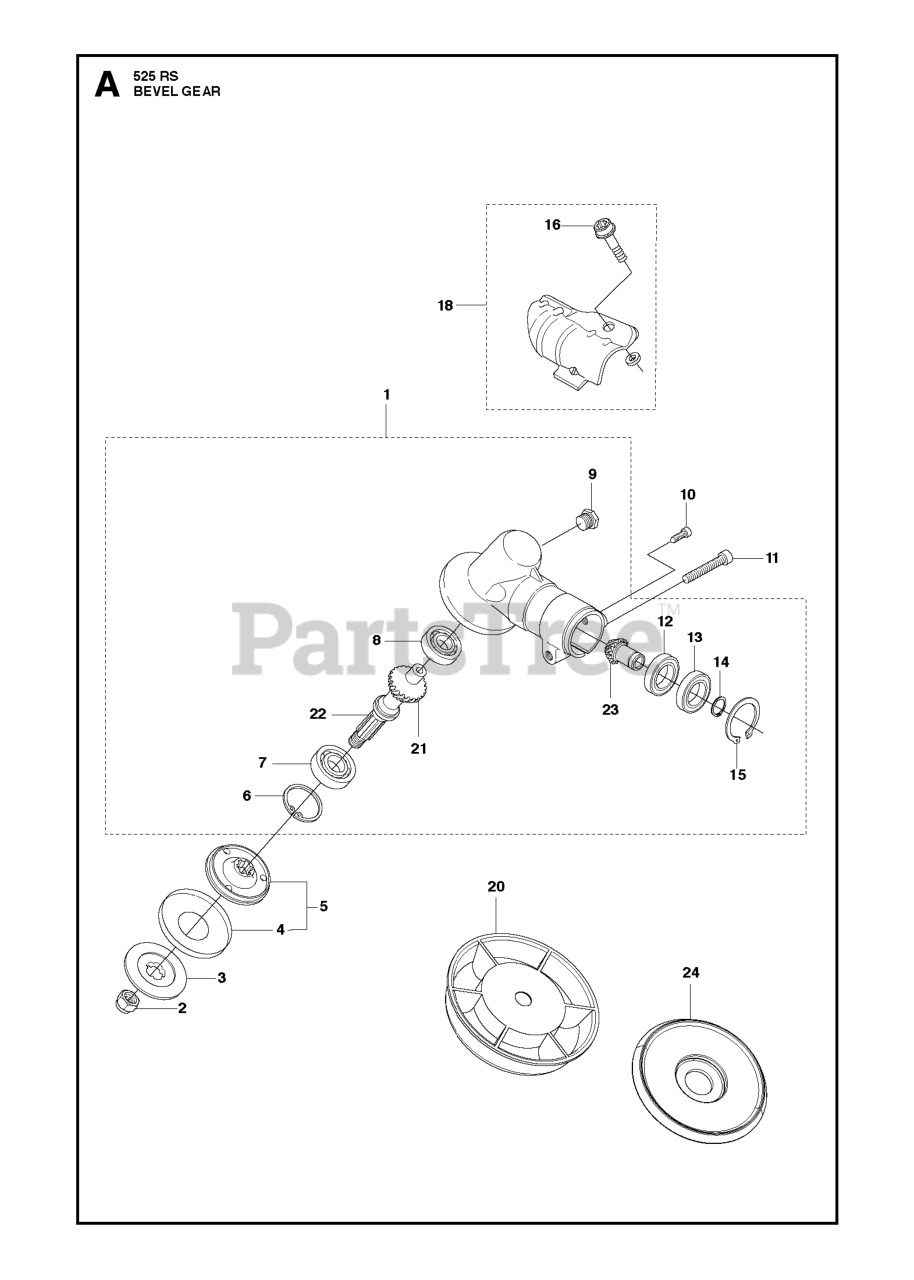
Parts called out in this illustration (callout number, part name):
2	GEARHEAD NUT - BRUSHCUTTER
3	SUPPORT FLANGE
4	WASHER
5	DRIVE DISC
6	RETAINING RING SGH 28
7	BEARING
8	BALL BEARING 8X22X7/608Z
9	PLUG
12	BALL BEARING 24X9X1/609ZR
14	RETAINING RING
15	RETAINING RING
20	SUPPORTING CUP
